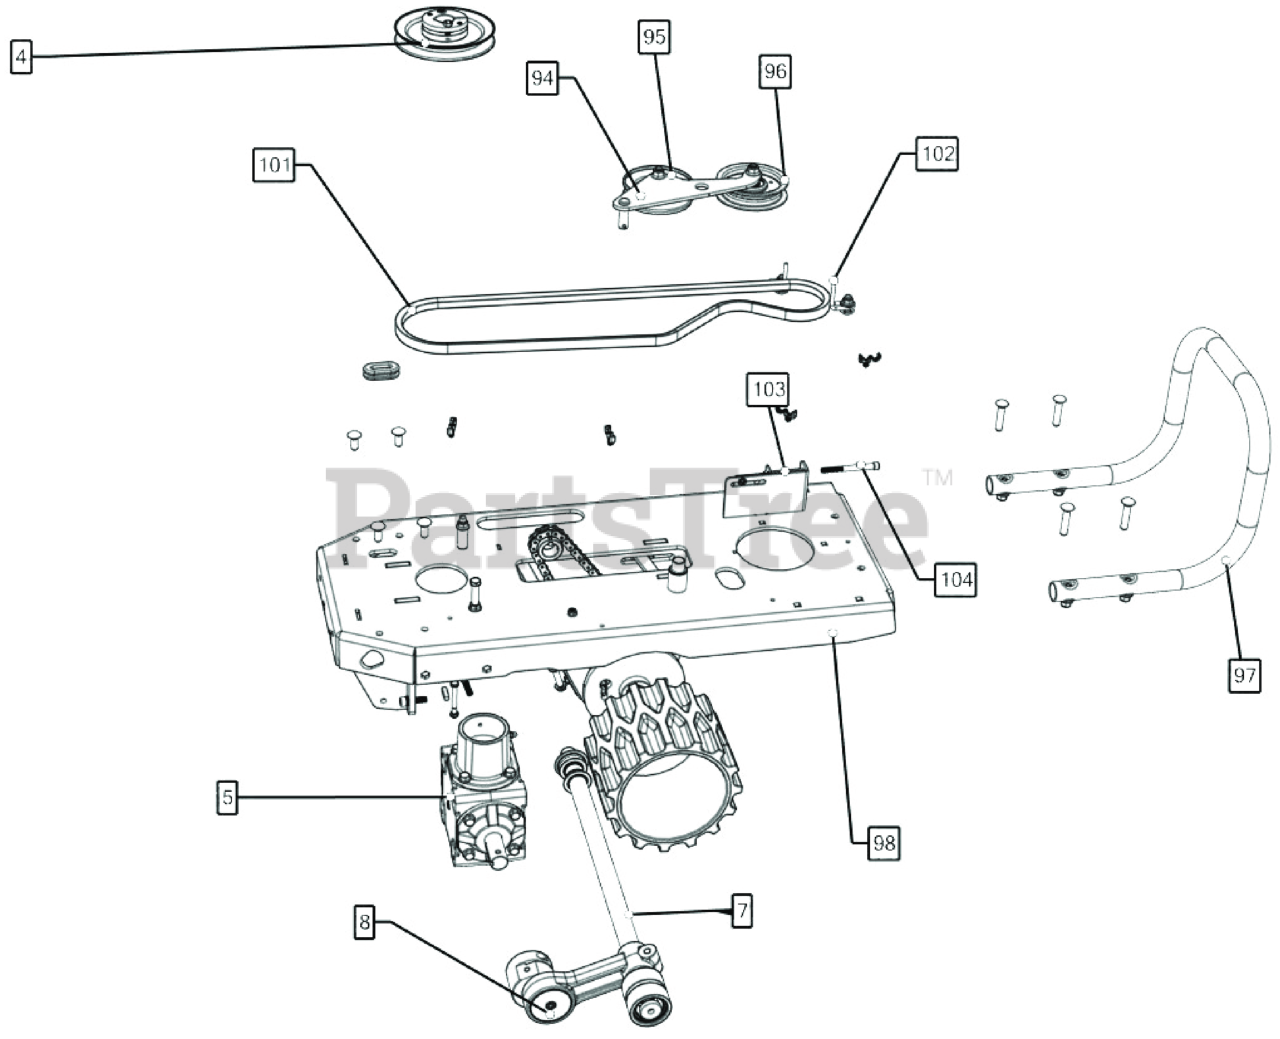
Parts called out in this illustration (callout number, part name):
4	PULLEY, BLADE DRIVE
5	GEARBOX, SPIRAL BEVEL 2:1 CURTIS
7	BAR, PUSH
8	WASHER, CONNECTING ROD
94	BELLCRANK, BLADE DRIVE SC181H
95	PULLEY IDLER INSIDE 4"
96	PULLEY IDLER 4" OD X 3/8"
97	TUBE BUMPER SC
98	BASE, FRAME SC181H
101	BELT, GATES 5L X 59 LNG BANDLESS
102	BELT FINGER AE900
103	SPRING, COMPRESSION 3.500" LNG X .480" O
104	SCR-CAP, SH .3125"-18 X 3.500" G8 ZP
